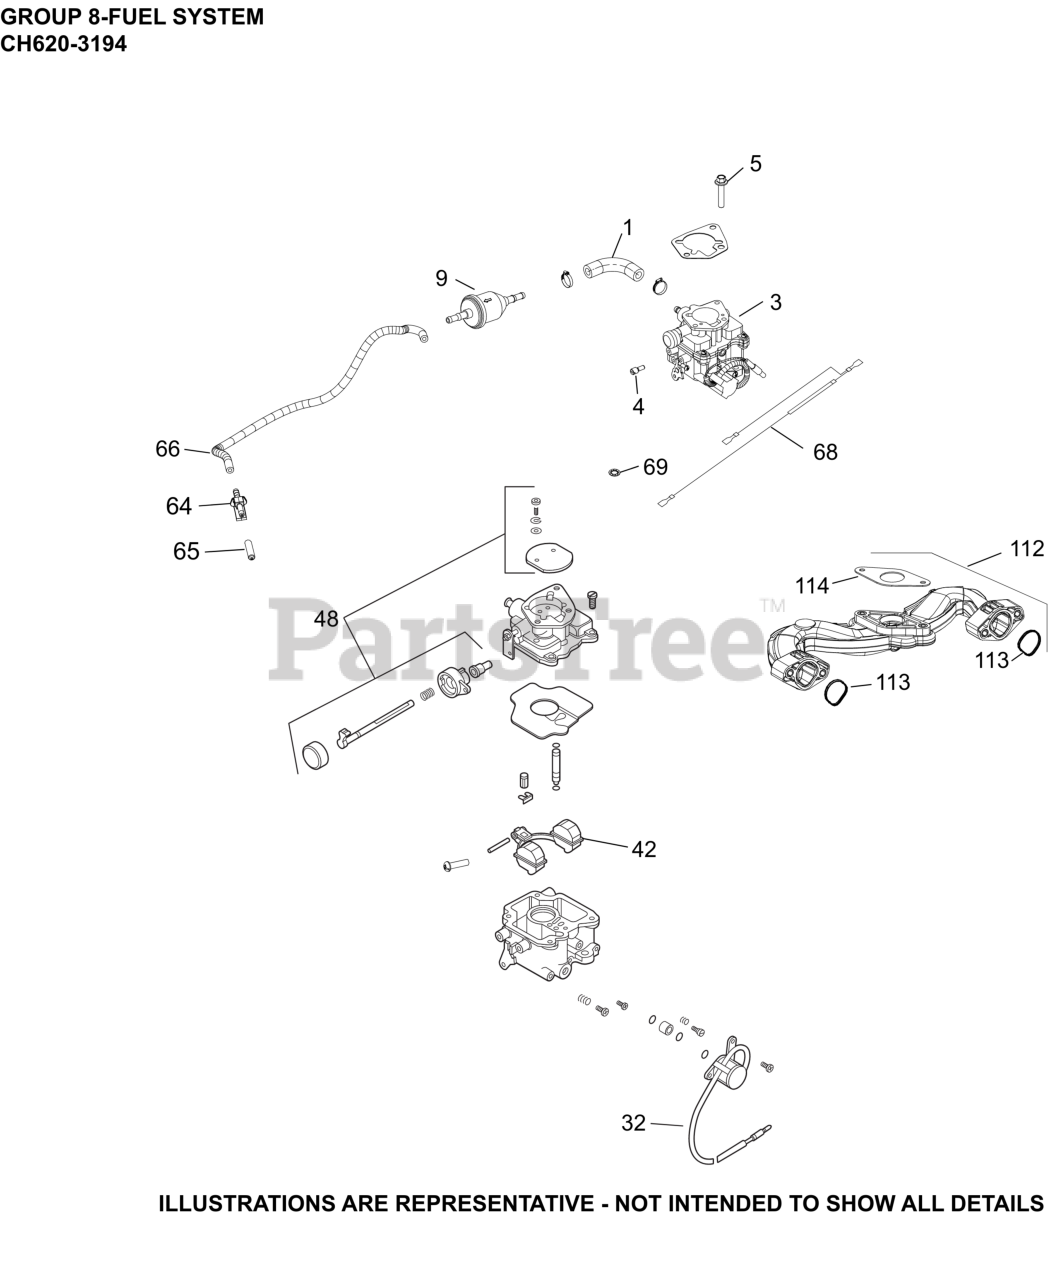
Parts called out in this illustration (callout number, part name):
1	HOSE,LW PERM.FUEL 24.00"-USE 25 111 81-S
3	KIT, CARBURETOR COMPLETE
4	SCREW, THROTTLE STOP
5	SCREW, FLG M6X1.0X25
9	FILTER, FUEL
32	KIT, SOLENOID
42	KIT, REPAIR FLOAT
48	KIT, REPAIR CHOKE
64	CONNECTOR, EVAPORATIVE
65	CAP, MASKING
66	HOSE, EVAPORATIVE 20"- (#24326143S)
68	LEAD, GROUND
69	WASHER, INT TOOTH LOCK 1/4"
112	INTAKE MANIFOLD W/GASKETS
113	O-RING, INTAKE PORT
114	GASKET, CARBURETOR (PIM, CH)
NI	KIT, HIGH ALT (4000-8000 FT)
NI	KIT, HIGH ALT (8,000+ FT)
NI	KIT, REPAIR CARBURETOR
